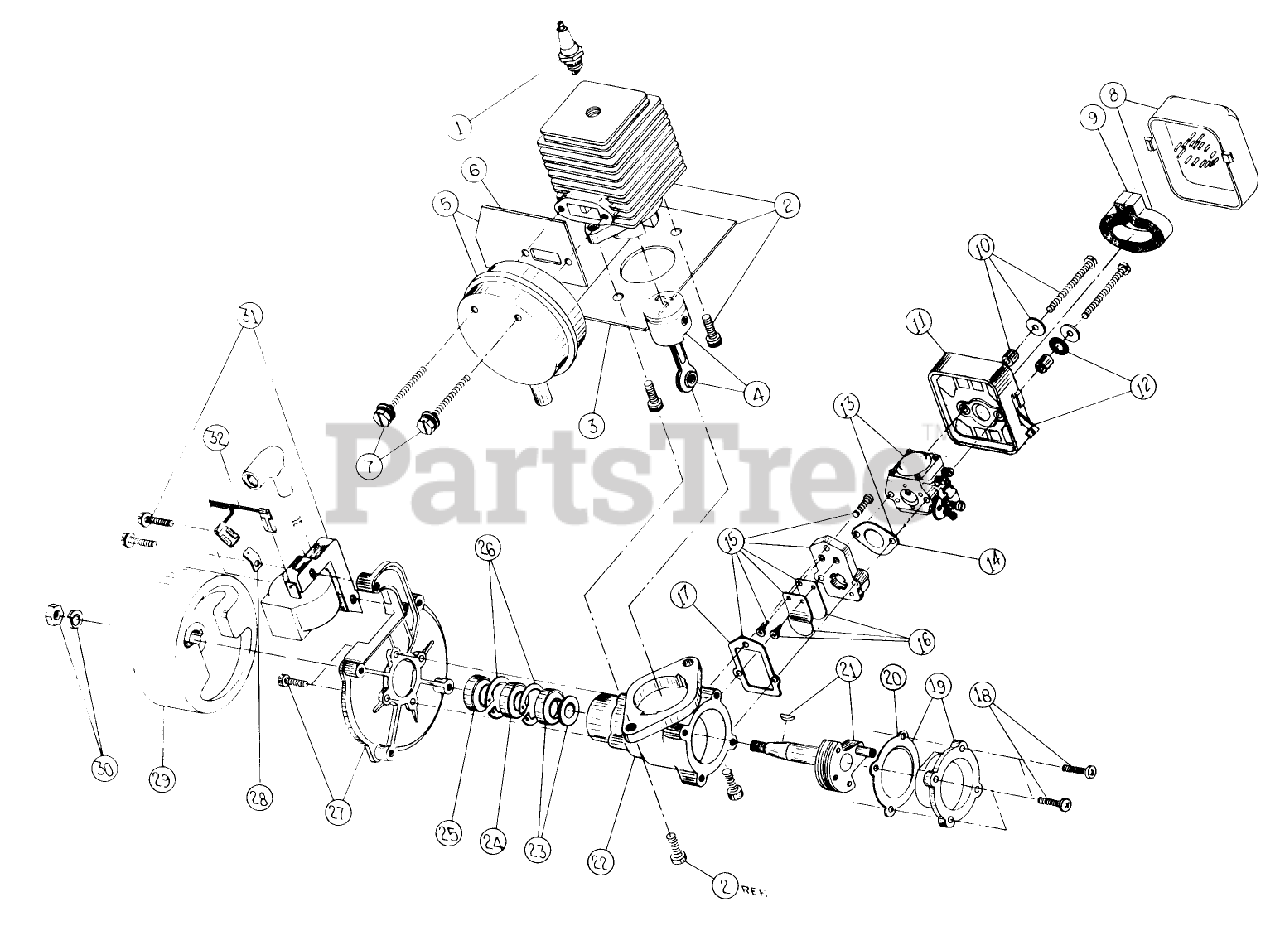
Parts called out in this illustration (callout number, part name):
1	SPARK PLUG
8	AIR CLEANER COVER ASM
23	INNER BEARING ASM
25	OUTER BEARING
38	FLYWHEEL KEY (10-PK)
